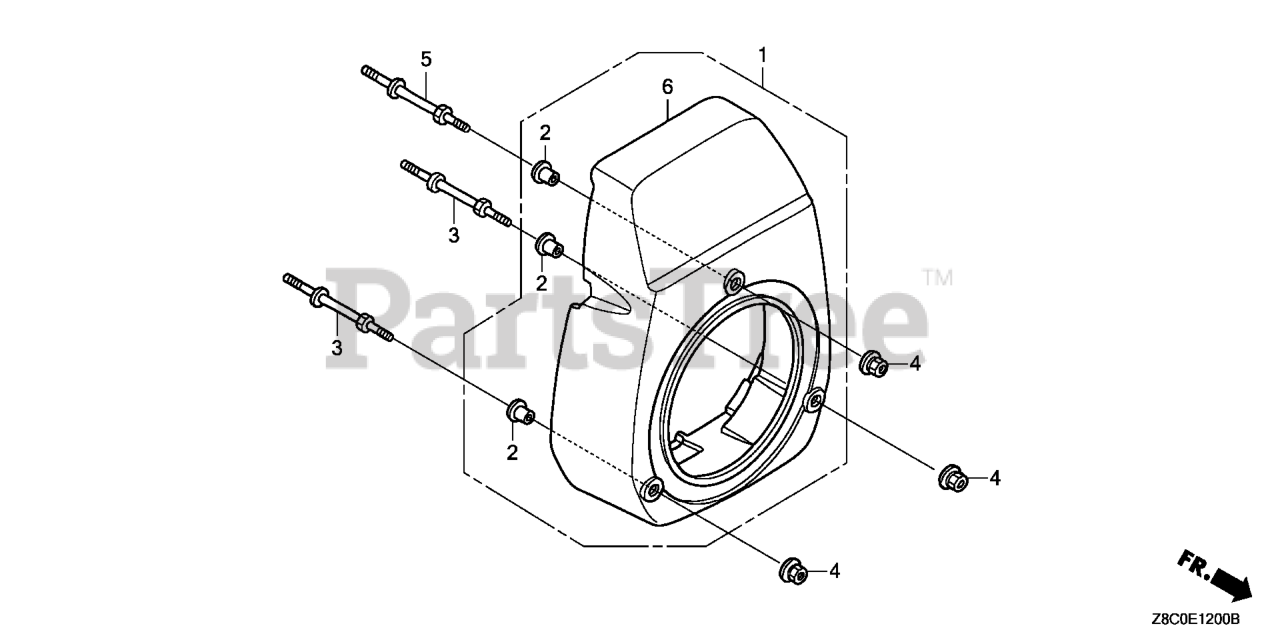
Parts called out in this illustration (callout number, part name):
3	BOLT, STUD (FAN COVER)
4	NUT, FLANGE (6MM)
5	BOLT, STUD (FAN COVER)
6	COVER, FAN *NH1* (BLACK)
6	COVER, FAN *R280* (POWER RED)
6	COVER,FAN *T114*
6	COVER,FAN *T113*
